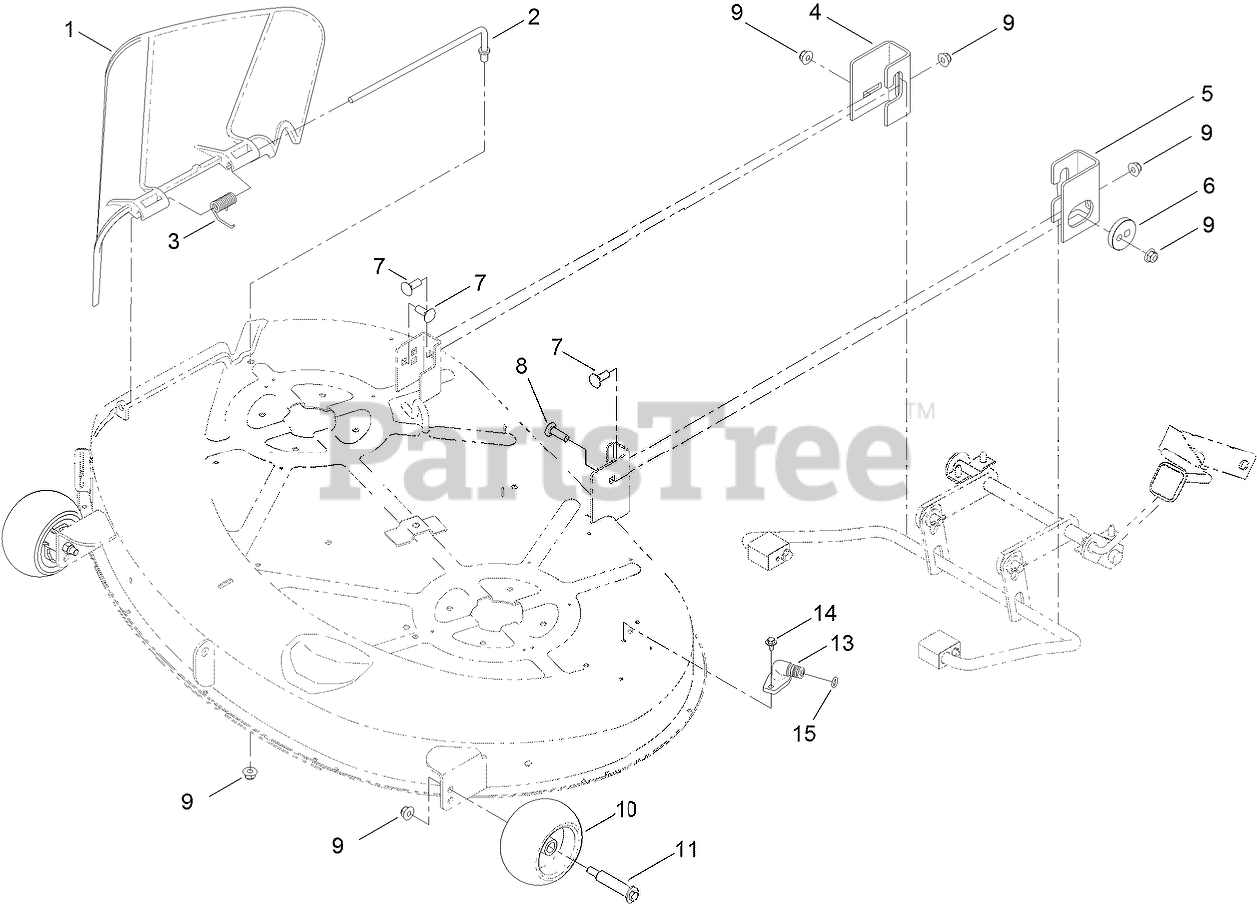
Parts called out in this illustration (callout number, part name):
1	DEFLECTOR
2	ROD-PIVOT
3	SPRING-TORSION
4	BRACKET-HANGER, RIGHT REAR
5	BRACKET-HANGER, LEFT REAR
6	ECCENTRIC
7	BOLT-CARR
8	SCREW-CARR
9	NUT-HF, NI
10	ROLLER-SCALP, ANTI
11	BOLT-SHOULDER
13	FITTING-WASHOUT
14	SCREW-HHFTF
15	O-RING
